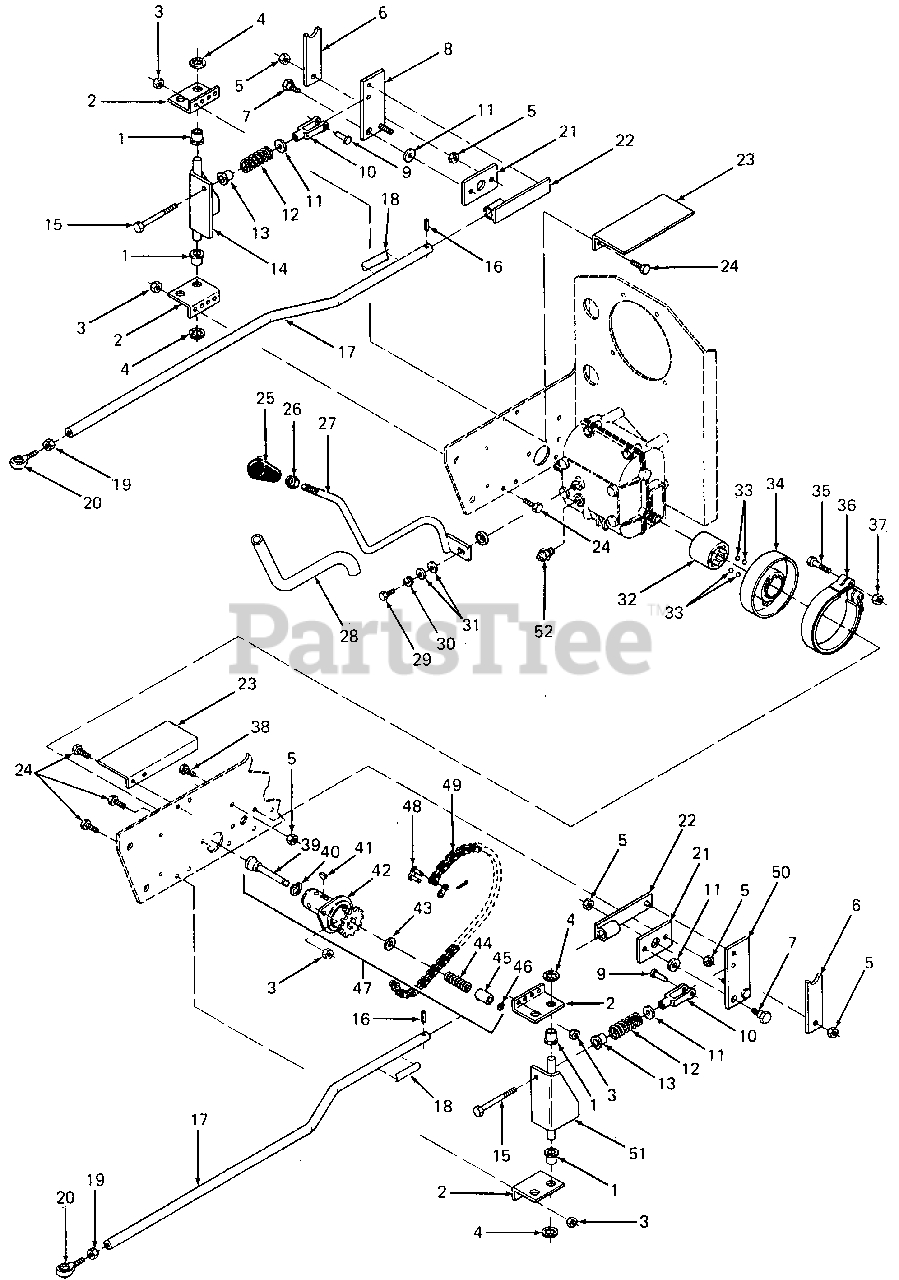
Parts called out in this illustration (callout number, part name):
1	Bushing, Flange
2	Bracket, Pivot
3	Nut, Hex Center Lock, 5/16-18
4	Push Ring, 5/8 Ext
5	Nut, Hex Center Lock, 3/8-16
7	Screw, Shld, 1/2 Dia X .295 Lg
8	Arm, Brake, LH
9	Pin, Clevis, 5/16 Dia X 3/4 Lg
11	Washer, Flat, 5/16
12	Spring, Wheel Clutch Actuator
13	Bushing, Flange
14	Actuator, LH
15	Screw, Hex Cap, 5/16-24 x 3.5 GR5
16	Pin, Spiral Spring, 1/4 Dia x 1.00 Lg
17	Rod, Steering Control
18	Decal, Lube Point
19	Nut, Hex Jam, 3/8-24
20	Rod End, Male
21	Plate, Brake Arm Mtg
22	Slider, Brake
23	Shield, Oil Drain
24	Screw, Hex Cap, 5/16-18 X .75 GR5
25	Knob, Control
26	Nut, Hex Jam, 1/2-13
28	Insulator, Shifter
29	Screw, Hex Cap, 1/4-28 X .75 GR8
30	Washer, Lock, 1/4
31	Washer, Flat, .281 ID X .73 OD X .063
32	Hub, Clutch
33	Ball, Steel, 3/8 Dia
34	Drum, Brake
35	Screw, Hex Cap, 3/8-16 X 1.75 Lg GR5
36	Band, Brake
37	Nut, Hex Jam, 3/8-16
38	Screw, Hex Cap, 3/8-16 X 1.5 Lg GR5
39	Plunger, Wheel Clutch
40	Ring, Internal Snap
41	Key, Hi Pro, 1/4 X 3/4 Dia
42	Shaft, Clutch
43	Washer, Wheel Clutch
44	Spring, Clutch Plunger
45	Sleeve, Wheel Clutch
46	Ring, External Snap
47	Shaft Assy, Wheel Clutch
48	Link, #50 Master
49	Chain, Final Drive
50	Arm, Brake, RH
51	Actuator, RH
52	Switch, Safety Start
